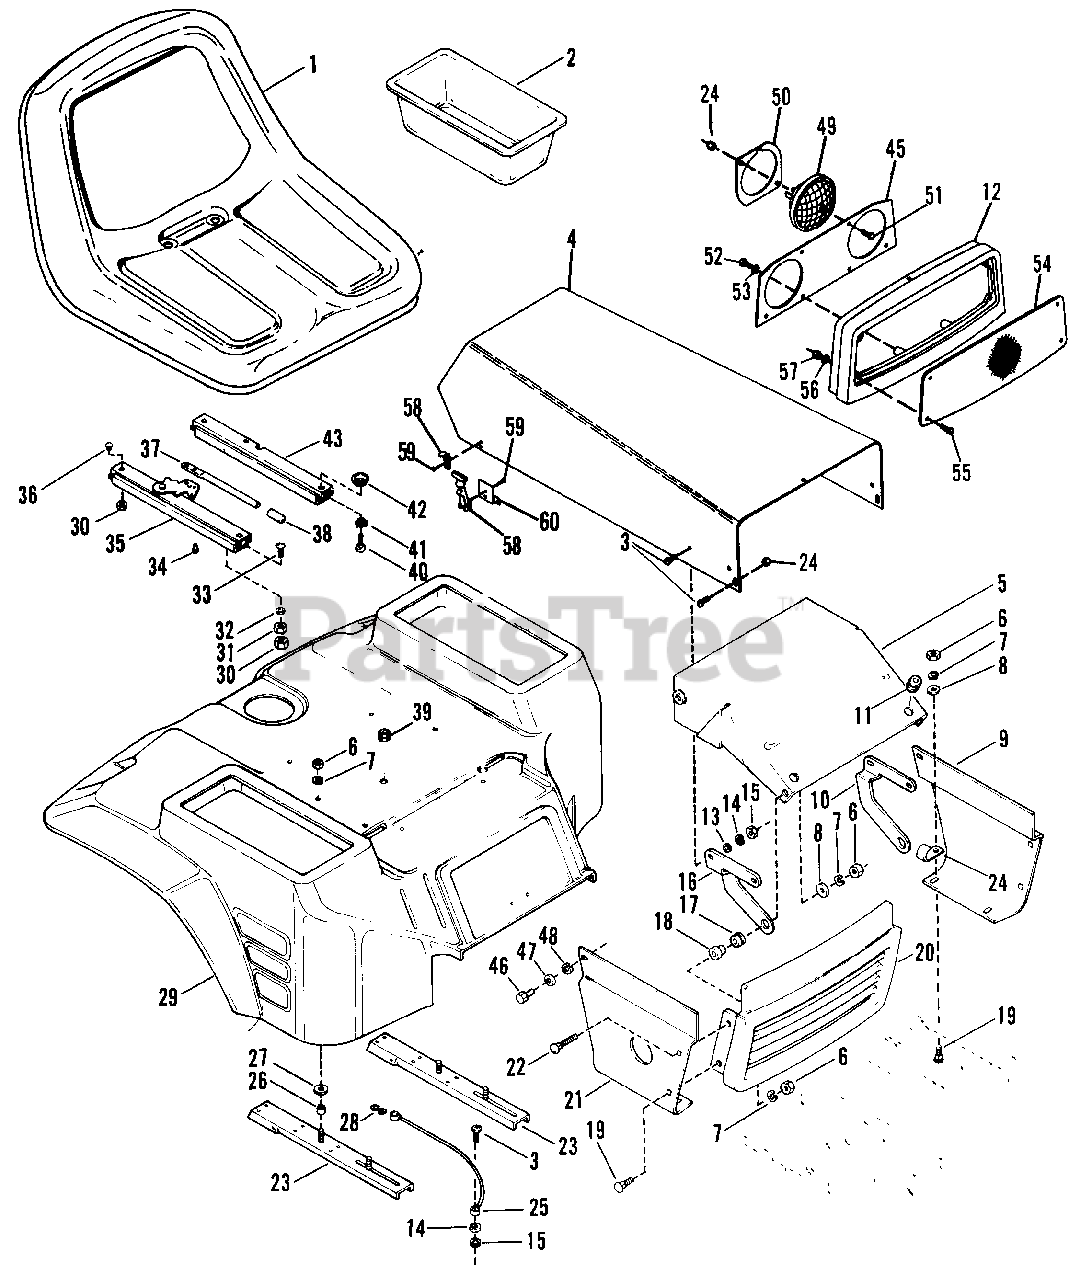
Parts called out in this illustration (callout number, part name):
1	Seat, High Back
2	Tray
3	Screw, Mach. 1/4-20 x .75 FHD
4	Hood, Tractor
5	Muffler Shield
6	Nut, Hex 3/8-16
7	Washer, Lock 3/8 Reg.
8	Washer, Flat .438 x 1.000 x .083
9	Side Sheet, L.H.
10	L.H. Hood Hinge
11	Grommet
12	Bezel, Headlight
13	Washer, Flat .281 x .625 x .065
14	Washer, Lock 1/4 Reg.
15	Nut, Hex 1/4-20
16	R.H. Hood Hinge
17	Grommet
18	Spacer
19	Bolt, 3/8-16 x 1.00 Rd Hd Sq Nk
20	Grill
21	Side Sheet, R.H.
22	Bolt, 3/8-16 x 2.00 Rd Hd Sq Nk
23	Seat Support
24	Nut, Lock 1/4-20
25	Cable
26	Spacer
27	Washer, .380/.390 x .750 x .125
28	"S" Hook
29	Rear Deck
30	Nut, Lock 5/16-18
31	Nut, Hex 5/16-18
32	Washer, Lock 3/8
33	Screw, Cap BTHD 5/16-18 x .875
34	Pop Rivet
35	Seat Slide, R.H.
36	Screw, Cap BTHD 5/16-18 x .50
37	Seat Slide Handle
38	Grip
39	Grommet
40	Screw, Mach. 5/16-18 x 1.00 Rd Hd
41	Washer, Lock 5/16 Ext.
42	Spacer
43	Seat Slide, L.H.
44	J-Clamp
45	Panel, Headlight Reflector
46	Screw, Machine 5/16-18 x .75
47	Washer, Lock 5/16 Int. Tooth
48	Washer, Flat .406 x .812 x .065
49	Headlight
50	Headlight Retainer Ring
51	Screw, Mach. 1/4-20 x 1.25
52	Screw, Tapping 1/4-20 x .625
53	Washer, Lock 1/4 Ext.
54	Panel, Headlight Lens
55	Screw, Mach. 10-24 x .75 PHD
56	Washer, Lock No. 10 Sp
57	Nut, Hex 10-24
58	Latch, Flexible
59	Rivet, Pop Domed 1/8 x .294
60	Bracket, Hood Latch Mtg.
NS	Decal, Side Stripe R.H. and L.H.
NS	Decal, 7173-H
NS	Decal, Gravely Logo
